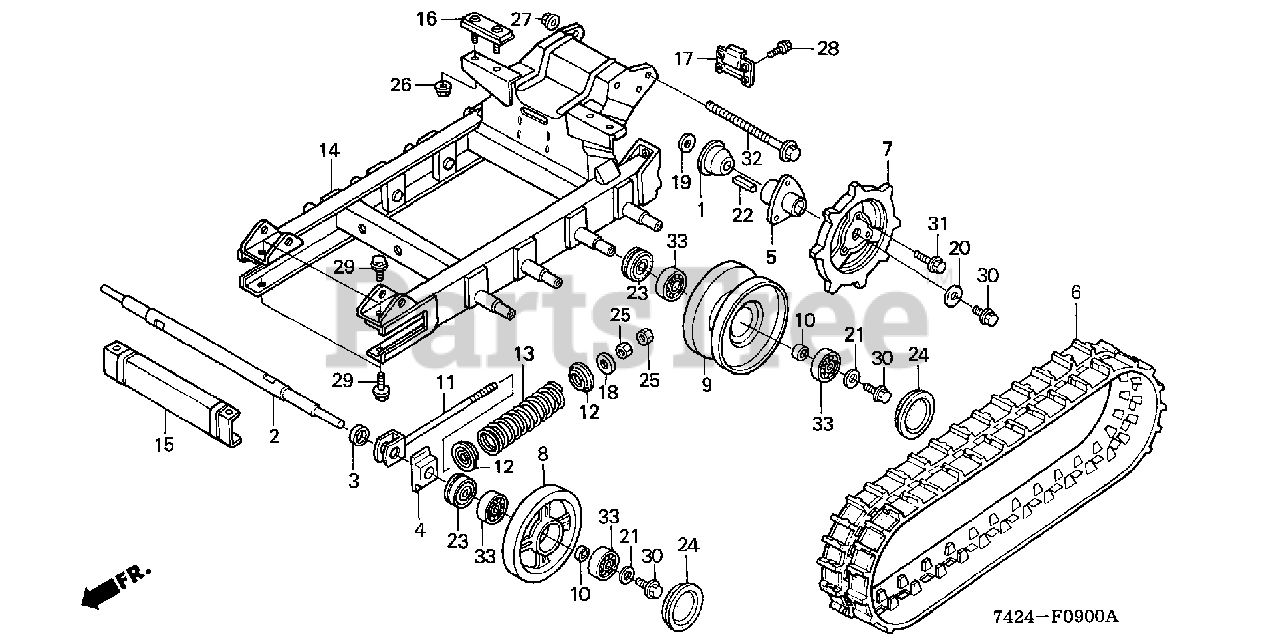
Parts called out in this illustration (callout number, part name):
1	GUARD, GRASS
2	SHAFT, FR. WHEEL *NH1* (BLACK)
3	COLLAR, FR. SHAFT
4	SLIDER, CRAWLER TENSION
5	HUB, CRAWLER SPROCKET
6	CRAWLER (60PX37L) *NH1* (BLACK)
7	WHEEL, DRIVE SPROCKET
8	WHEEL, DRIVEN *NH1* (BLACK)
9	WHEEL, INDUCTION
10	COLLAR, WHEEL
11	BOLT, CRAWLER TENSION
12	HOLDER, TENSION SPRING
13	SPRING, CRAWLER TENSION
14	FRAME *NH1* (BLACK)
15	CROSSMEMBER, FR.
16	RUBBER, CARRIER MOUNTING
17	PLATE, DUMP LOCK
18	WASHER (12.2X33X3.2)
19	WASHER, THRUST (22X39X2)
20	WASHER (10.5MM)
21	WASHER, SPECIAL (10MM)
23	OIL SEAL (24X47X15)
24	PLUG, SEAL (47X10)
25	NUT, HEX. (12MM)
26	NUT, FLANGE (6MM)
27	NUT, FLANGE (10MM)
28	BOLT, FLANGE (8X16)
29	BOLT, FLANGE (8X20)
30	BOLT, FLANGE (10X25)
31	BOLT, FLANGE (10X32)
32	BOLT, FLANGE (10X160)
33	BEARING, RADIAL BALL (6204)
